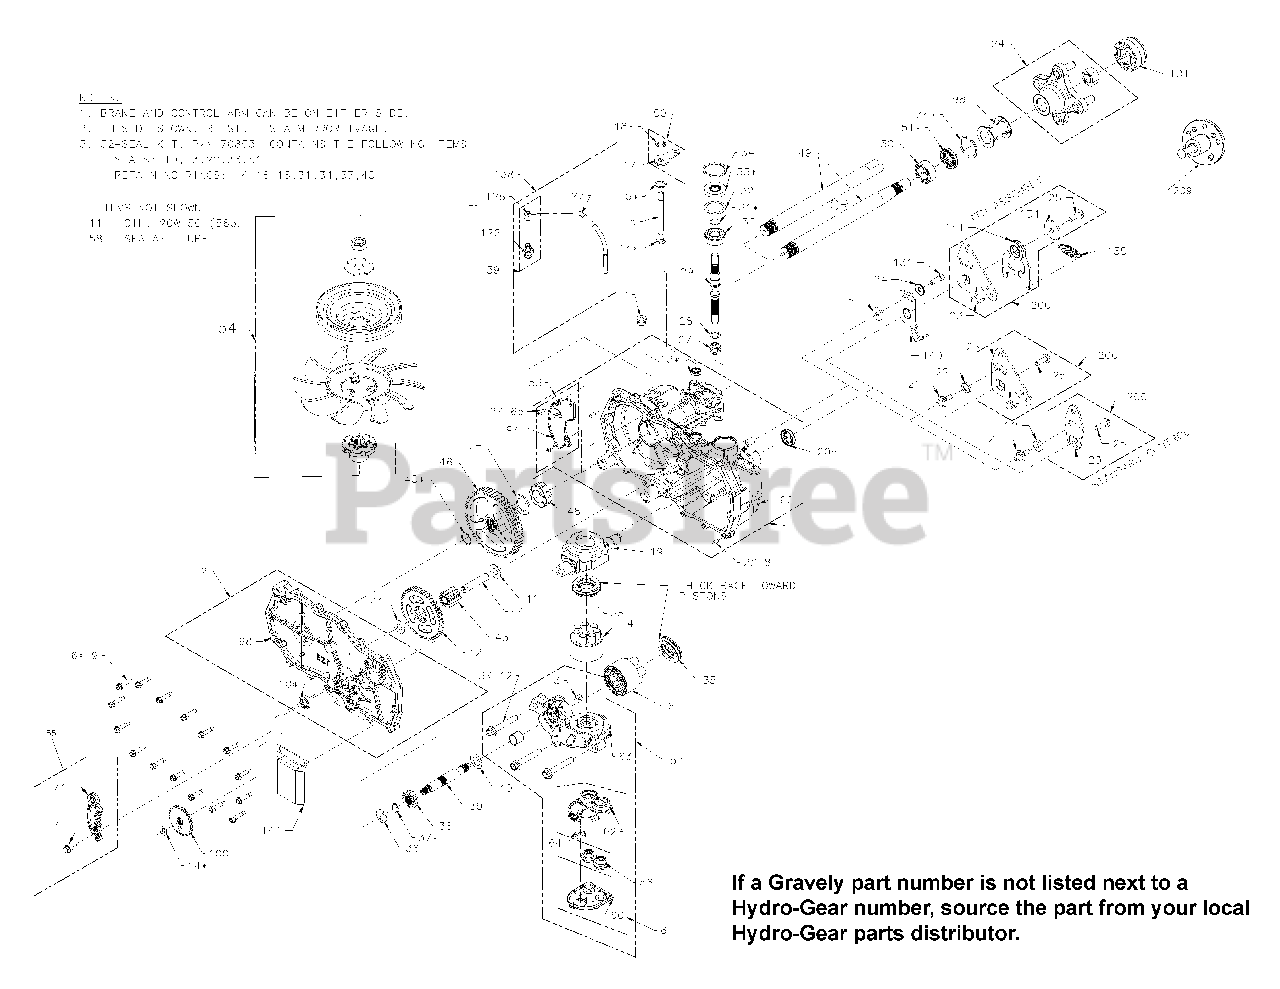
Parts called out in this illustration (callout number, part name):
1	KIT, MAIN HOUSING W/CNTL, LH
2	COVER, SIDE, LH W/BRAKE
4	ASSEMBLY, PISTON BLOCK - 7P IOCC
5	SPACER, .320 X 1.005 X .179
6	ASSEMBLY, PISTON BLOCK - 5P IOCC
9	HFHCS 1/4-20 X I.I25
15	ROD, BYPASS
19	SWASHPLATE, TRUNNION, MACHINED
24	WASHER, .34 X .88 X .06
27	SPRING, HELICAL COMPRESSION
28	WASHER, .591 X .787 X .040
29	SHAFT, INPUT
30	BEARING, BALL 17MM ID X 40MM OD X 12
32	SPACER
33	SEAL, LIP 1 7 X 40 X 7
34	RING, RETAINING
35	BEARING, THRUST 30 X 52 X 13
36	WASHER, 5/8 X I.0 X .05
37	RING, RETAINING
38	GEAR, PINION 13T
39	SHAFT, MOTOR
40	WASHER, .7I X I.I6 X .04
41	WASHER, HT .5 ID X I.0 OD X .032
42	GEAR, 10T/48T
43	GEAR, 10T JACKSHAFT
44	PIN, JACKSHAFT
52	KIT, SEAL
53	PLATE EXPANSION, LH
54	KIT, FAN-PULLEY
55	KIT, BRAKE ARM, THROUGH HOLE
58	SEALANT TUBE
59	KIT, BYPASS ARM W/ THRU HOLE
61	KIT, FILTER
100	DISC, COG BRAKE
135	SPRING, EXTENSION CLEAR ZINC
140	ARM, NEUTRAL LEFT
209	HUB PULLER
